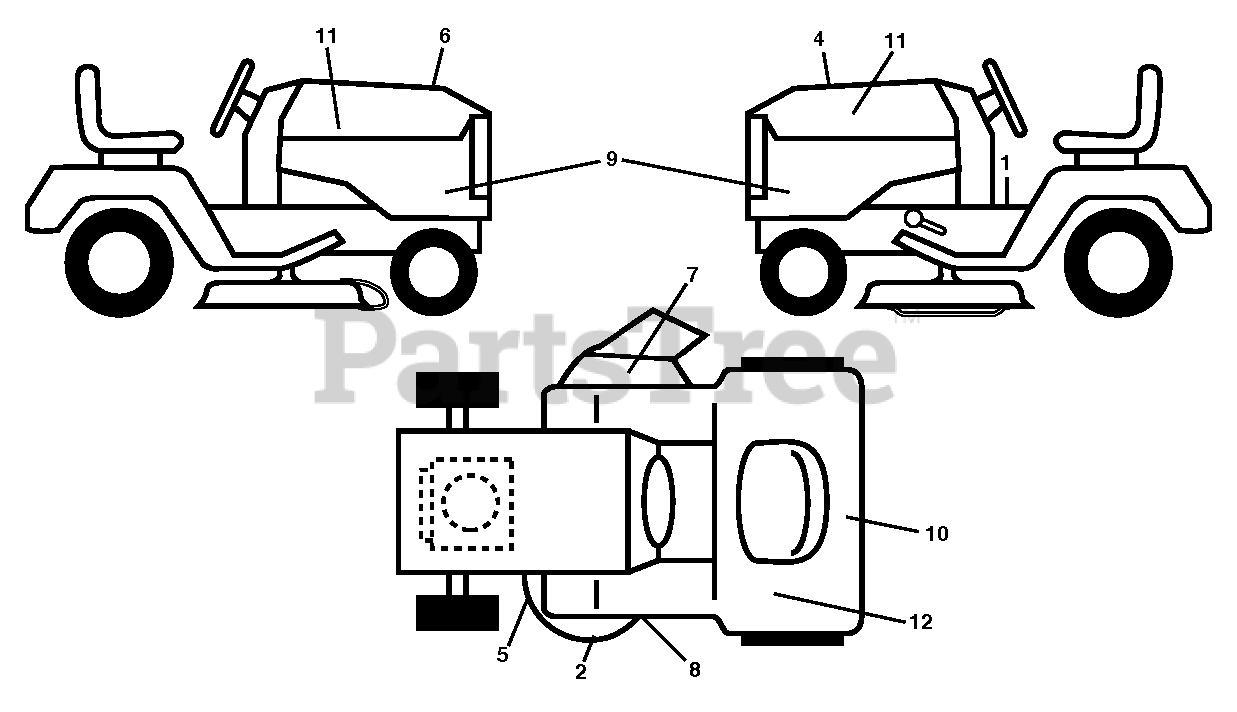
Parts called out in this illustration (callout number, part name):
1	DECAL.WARNING.2007.ENG/FR
2	DECAL.DECK.STAMP.BIOCLIPCMP.HU
6	DECAL.E85.WARNING.2012
7	DECAL, DECK DEFLECTOR, WARNING
8	DECAL.MOWER.SCH.48/54.PREM
9	DECAL.SIDE.PANEL.YTH24K48
11	DECAL.BADGE.170MM.TEXTLOGO.
12	DECAL.DECK.BUILTINAMERICA.HUSQ
